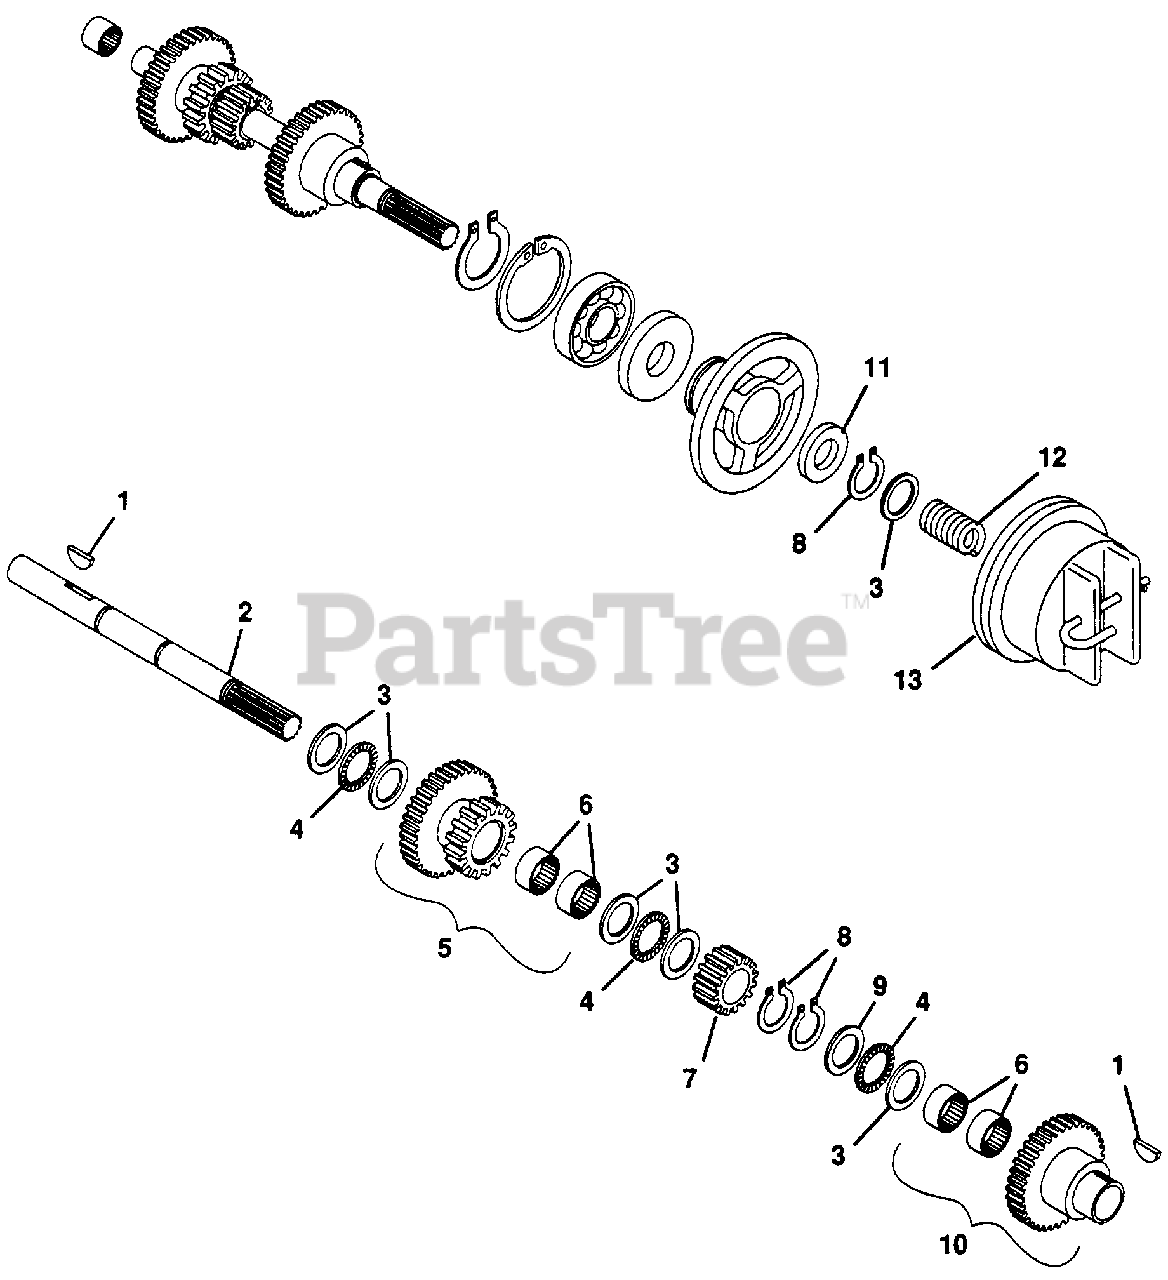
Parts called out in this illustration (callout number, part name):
1	Key, Woodruff .188x.625 Hrd #61
2	Shaft, Splined Rev Clutch
3	Race, Brg Thrust .752x1.240x.030
4	Brg,NeedleThrust .752x1.24x.078
5	Assembly, Idler Gear
6	Bearing, Needle .75x1x.50
7	Gear, 10 DP 16 Teeth x .750 Std.
8	Ring, Retaining .750 Shaft
9	Race, .060 Bearing Thrust
10	Assembly, Reverse Gear and Brg
11	Seal, Oil .750x1.625x.250
12	Spring, Comp. 1.0x.80x36 lb/in
13	Number 11 - Fwd-Rev Clutch Asm.
